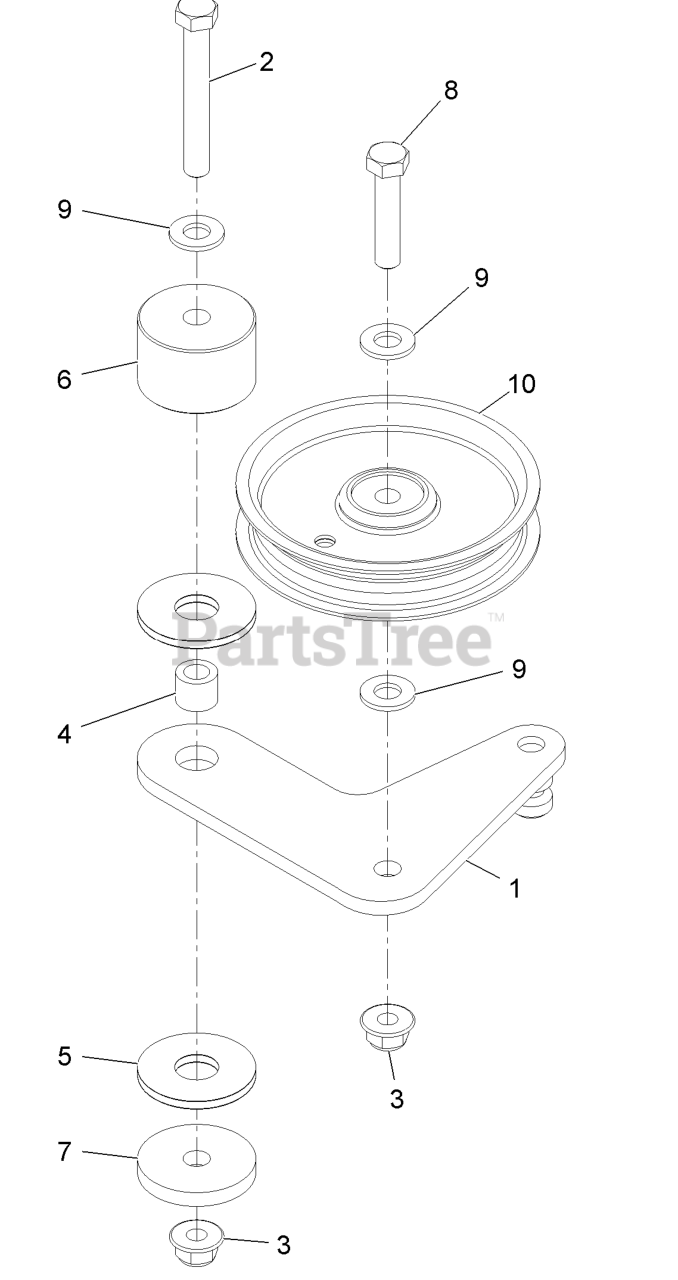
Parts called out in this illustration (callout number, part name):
1	PLATE-IDLER
2	SCREW-HH
3	NUT-HF, NI
4	BUSHING-LEVER, LIFT
5	WASHER-FRICTION, COMPOSIT
6	HUB-IDLER
7	WASHER-PLAIN
8	SCREW-HH
9	WASHER-FLAT
10	PULLEY-IDLER
